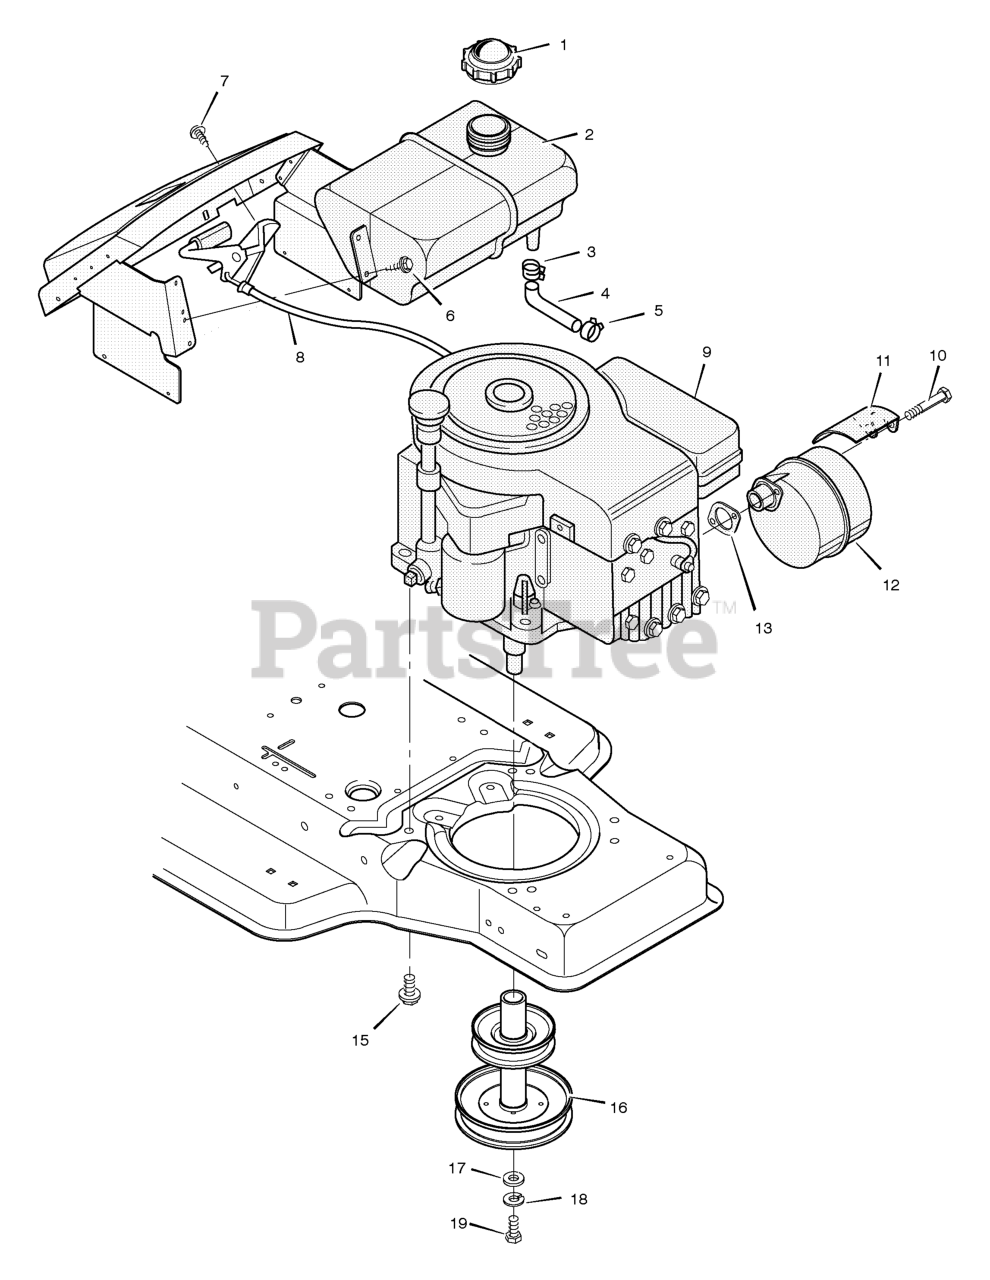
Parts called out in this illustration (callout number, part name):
1	Fuel Cap
2	Fuel Tank
3	Hose Clamp
4	Fuel Line
5	Hose Clamp
8	Throttle Control
9	Engine *
11	Shield, Heat
12	Muffler
13	GASKET, Exhaust
15	Bolt, Engine Mount
16	Pulley, Stack
18	Lockwasher
19	Bolt, Hex
